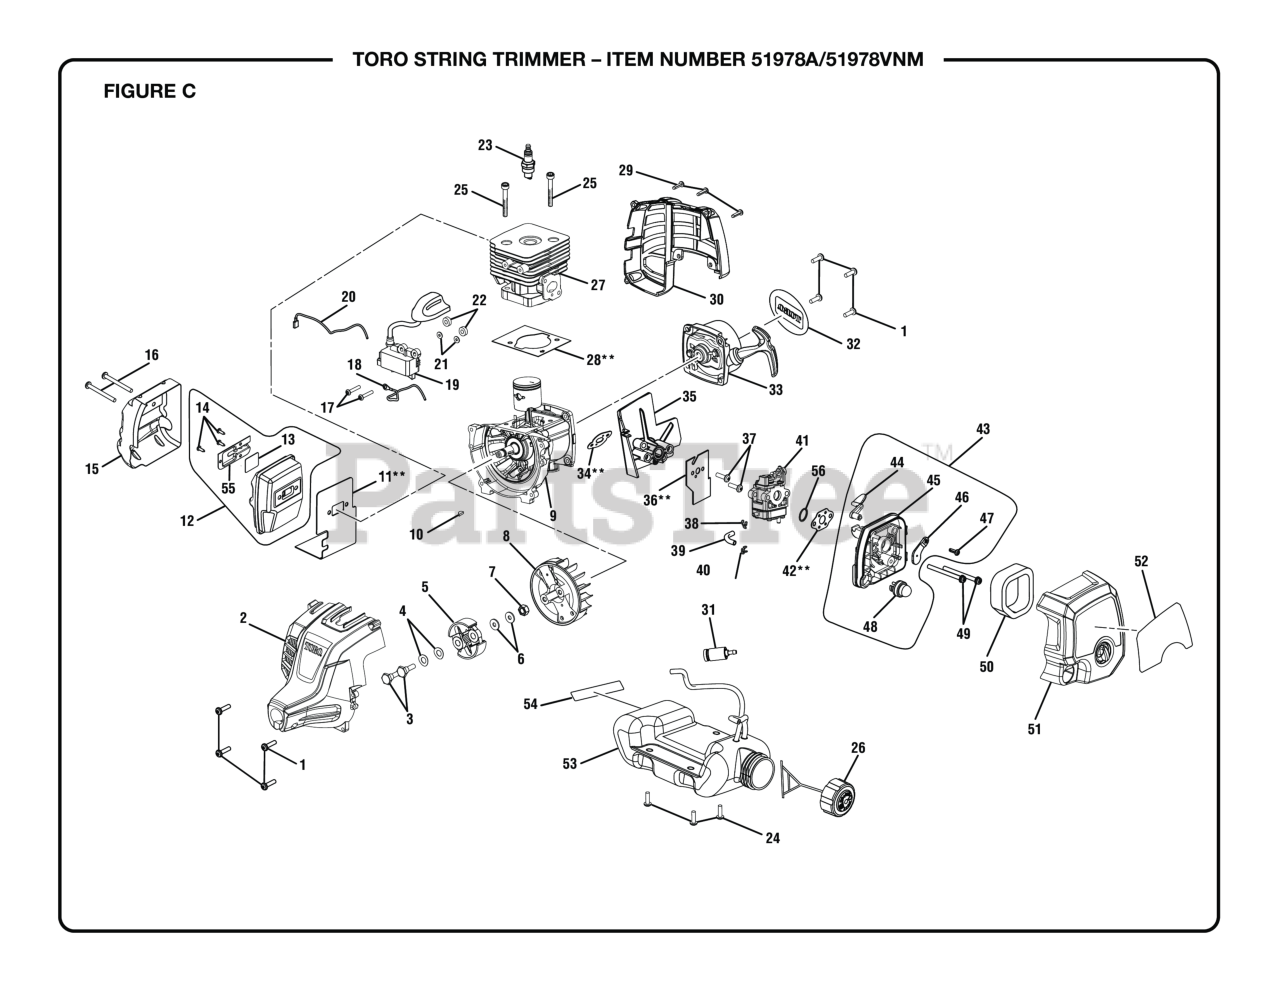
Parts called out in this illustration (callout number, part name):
1	Cap Screw w/Washer (M5 x 16 mm, T25 Torx Soc. Hd.)
2	Front Housing Assembly
3	Clutch Shoulder Bolt (M6 x 22.5 mm, Hex Hd.)
4	Washer (Curved)
5	Clutch Assembly
6	Washer (ID6 x OD15 x 1.2t)
7	Flange Nut (M8, Flywheel)
9	Crankcase Assembly.
10	WOODRUFF KEY (10 mm X 3 mm)
11	Muffler Gasket
12	Muffler Assembly (Inc. Key Nos. 3-4)
13	SCREEN
14	Screw (6-20 x 1/4 in., T20 Torx Pan Hd. S.T.)
15	HEAT SHIELD
16	Screw (M5 x 50 mm, Torx Slotted Recessed Pan Hd.)
17	Screw (M4 x 22 mm, T20 Torx Slotted Recessed Pan Hd.)
18	Lead Wire Assembly, Red
19	Coil Boot Assembly
20	Lead Wire Assembly, Black
21	Flat Washer (OD10 x ID42 x 1t)
22	Phenolic Spacer (Ignition Module)
23	SPARK PLUG (CHAMPION RCJ4)
24	Shoulder Screw w/Washer (M4 x 14 mm, T25 Torx Truss Hd.)
25	Screw (M5 x 22 mm, T25 Torx Soc. Hd.)
26	Fuel Cap Assembly
28	Gasket
29	Screw (M4 x 18 mm, T20 Torx Pan Hd. S.T.)
30	Rear Engine Housing
31	Fuel Filter
32	Logo Label (Rear)
33	Starter Recoil & Starter Cup Assembly
34	Heat Dam Insulator
36	Gasket
37	Screw w/Washers (M5 x 30 mm, T25 Torx Pan Hd.)
38	Clip-hose (Id 4.9)
39	Fuel Line (45 mm)
40	CLIP-HOSE (ID 4.9)
41	CARBURETOR ASSEMBLY
42	Carburetor Gasket
43	Filter Housing Assembly
44	CHOKE LEVER
45	CARBURETOR PLATE
46	Screw (M4 x 12 mm, T20 Torx Pan Hd. S.T.)
47	Screw (M4 x 12 mm, Slotted Recessed Pan Hd.)
48	Primer Bulb Assembly
49	Screw (M5 x 44 mm,T25 Torx Hd. Carburetor)
50	Air Filter (Element)
51	Airbox Cover Assembly w/Label
52	Starting Instructions Label
53	Fuel Tank & Cap Assembly
54	Combustion Warning Label
55	Trimmer Outlet
